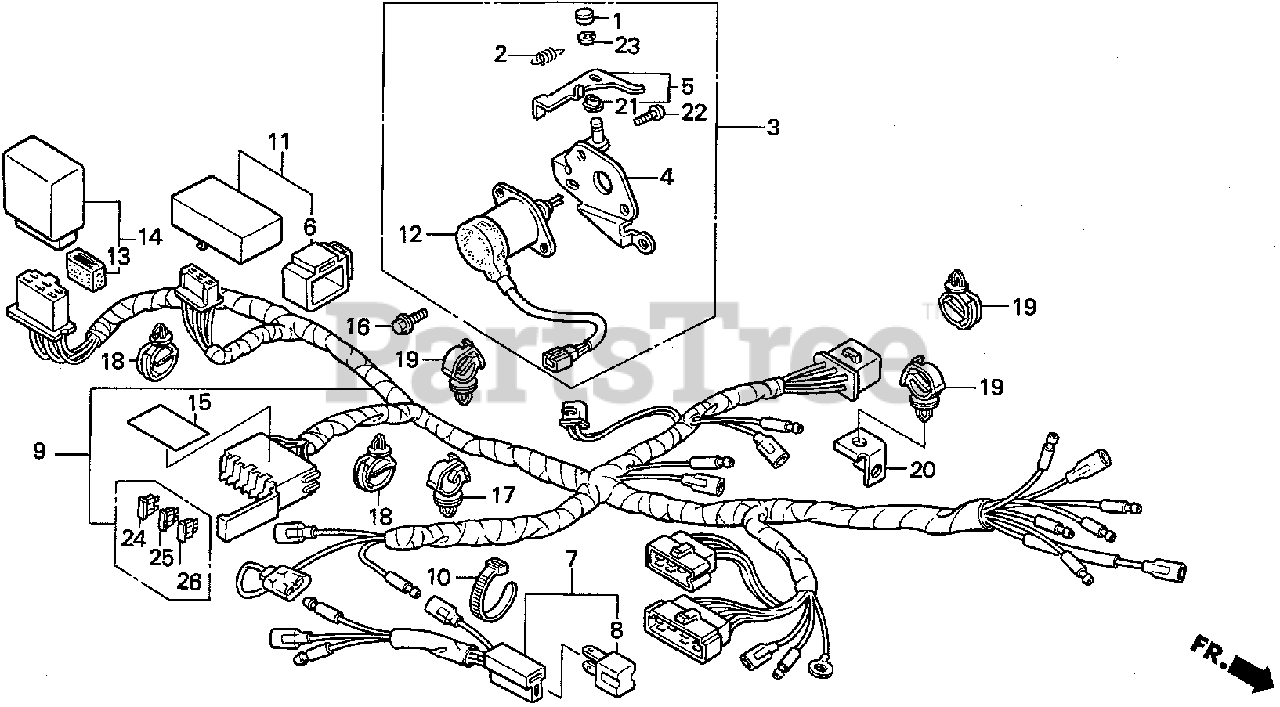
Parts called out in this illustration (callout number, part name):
1	CAP, CHOKE LEVER
2	SPRING, CHOKE RETURN
3	THROTTLE ASSY., AUTO (NOT AVAILABLE)
4	STAY, SOLENOID THROTTLE
5	LEVER, SOLENOID THROTTLE
6	RUBBER, IGNITION CONTROL MODULE
7	DIODE ASSY., SOLENOID
9	SUB-WIRE HARNESS ASSY.
10	BAND B1, CABLE
11	CONTROL UNIT ASSY., SOLENOID
12	SOLENOID ASSY.
13	SUSPENSION, TURN SIGNAL RELAY
14	TIMER UNIT
15	LABEL, FUSE
16	BOLT, FLANGE (6X12) (CT200)
17	CLIP (20MM)
18	CLIP, WIRE HARNESS
19	CLIP, HARNESS
20	BASE, WIRE CLIP
21	BUSH, AUTO-THROTTLE LEVER
22	SCREW, PAN (5X8)
23	E-RING (4MM)
24	FUSE, BLADE (1A)
25	FUSE, BLADE (5A)
26	FUSE, BLADE (10A)
